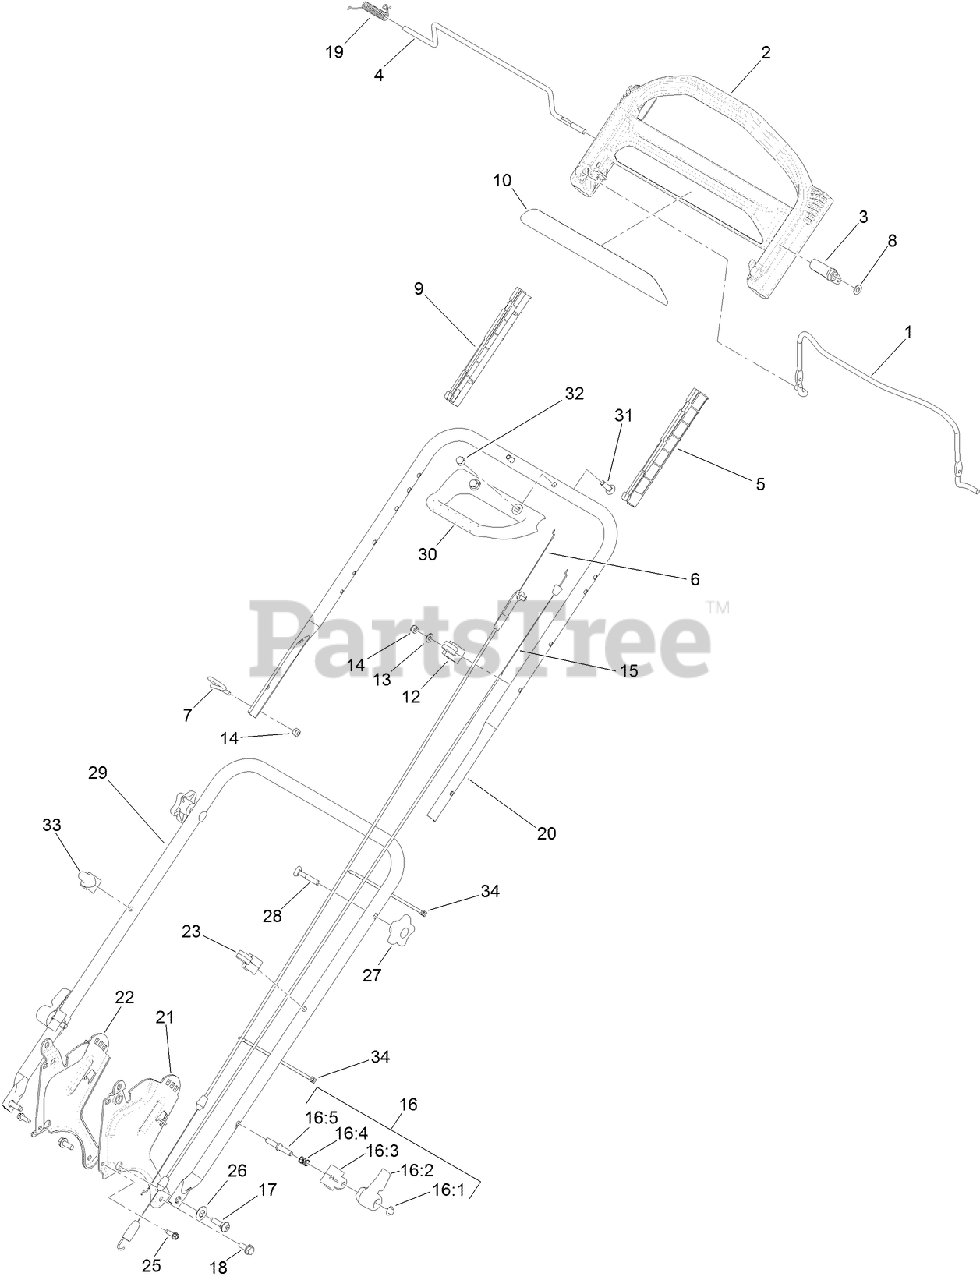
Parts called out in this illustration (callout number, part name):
1	BAIL-BRAKE
2	HANDLE-CONTROL
3	LEVER-TRACTION
5	GUIDE-LH
6	CABLE-BRAKE
7	GUIDE-ROPE
8	WASHER-PLAIN
9	GUIDE-RH
10	DECAL-HANDLE
12	ANCHOR-CABLE
13	WASHER-FLAT
14	NUT-LOCK, NI
15	CABLE-TRACTION
16	QUICK RELEASE ASM
16:2	LEVER
16:3	ANCHOR-SPRING
16:4	SPRING-COMPRESSION
16:5	ROD-RELEASE
17	SCREW-SHOULDER, BHTF
18	SCREW-THD ROLL, HWH
20	HANDLE-UPPER
21	BRACKET-HANDLE, LH
22	BRACKET-HANDLE, RH
23	GUIDE-CABLE
25	SCREW-HWHTF
26	WASHER-SPRING, CONICAL
27	KNOB-HANDLE
29	HANDLE-LOWER
30	HANDLE-ASSIST, TRACTION
31	BOLT-CARRIAGE
32	NUT-ACORN
33	GUIDE-ROPE, FLEXIBLE
34	TIE-CABLE
